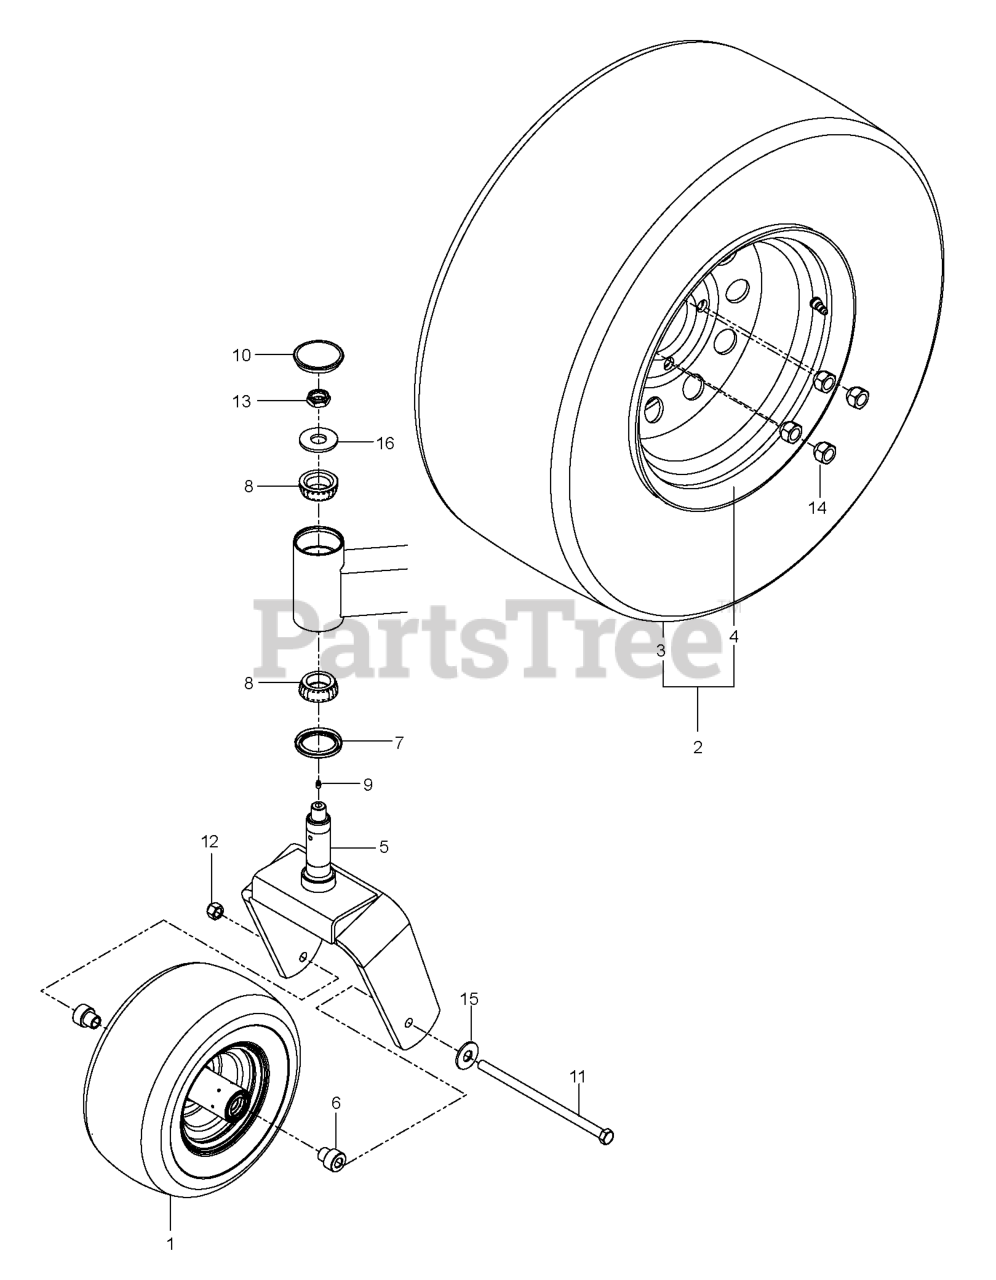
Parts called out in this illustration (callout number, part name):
1	TIRE, 13 X 6.5-6 NO FLAT
2	WHEEL/TIRE.ASM.24X12-12.SILVER
3	TIRE.24X12-12.TURF.MASTER
4	RIM, 12 X 8.5 W/1.75 NEG OS
5	FORK.CASTER.ORANGE
6	AXLE SPACER
7	SEAL, BEARING
8	CONE, LM67048
9	ZERK
11	HEX SCREW 1/2-13 X 9.5 GR5
12	NUT, 1/2-13 HEX FLG NYLOC ZD
13	NUT, 3/4-16 HEX THIN NYLOC ZD
14	LUG NUT 1/2F
15	WASHER 1/2" FLAT
16	WASHER, 3/4 HARDENED
